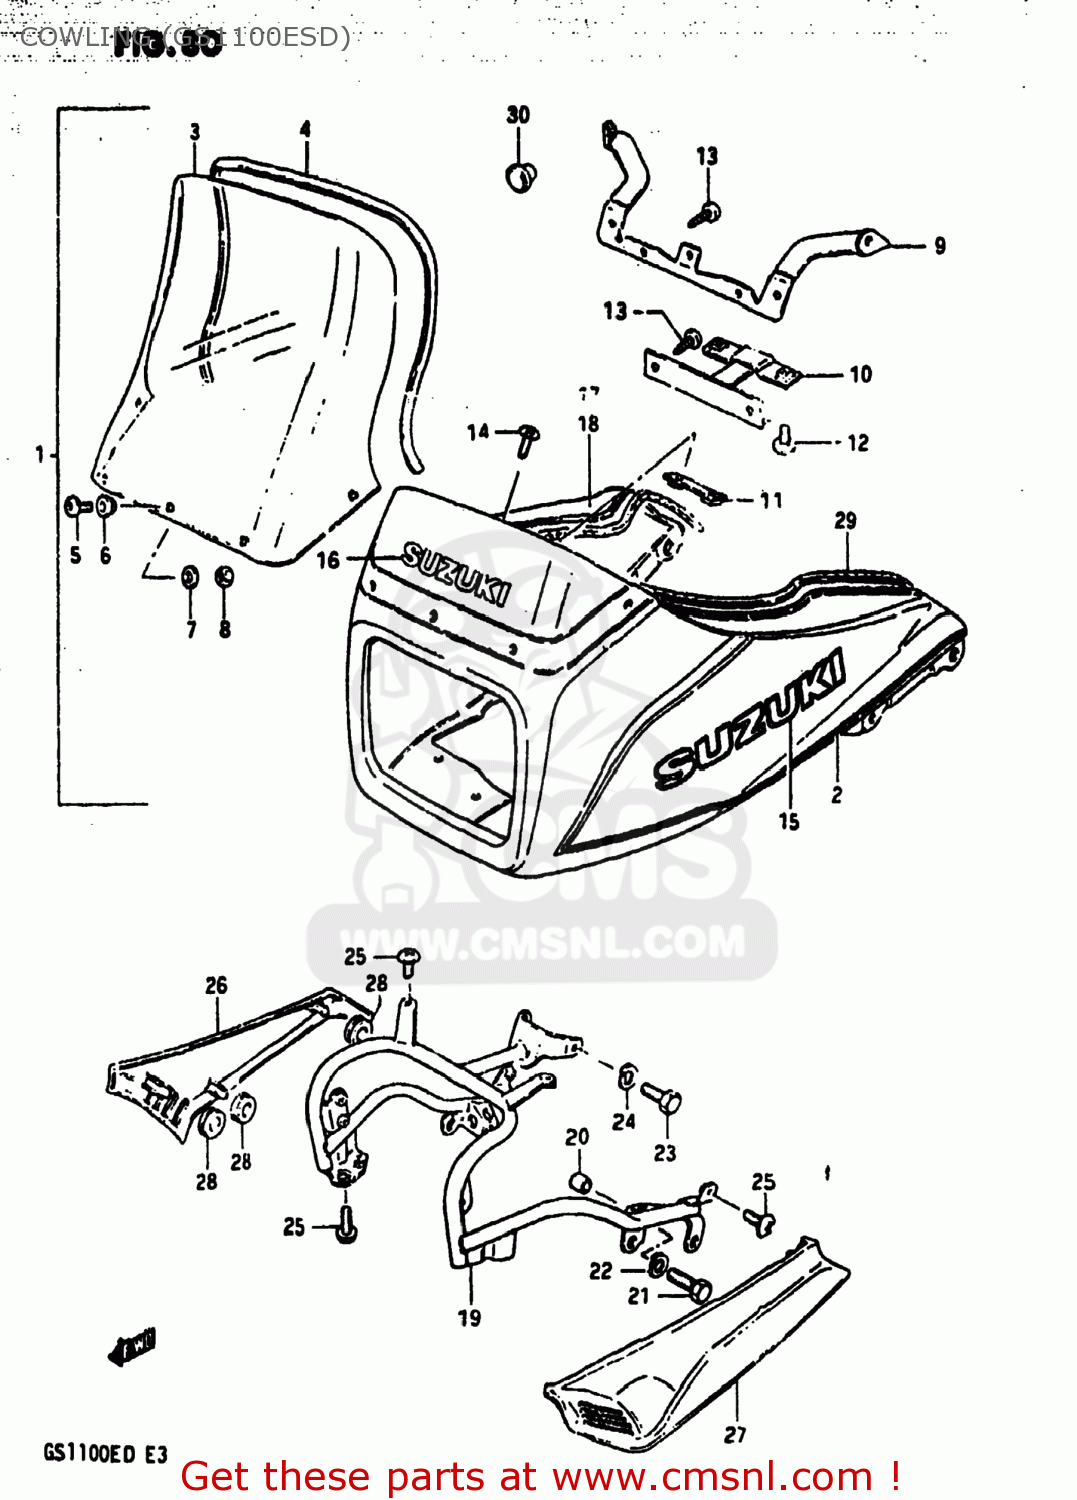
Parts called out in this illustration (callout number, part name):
1	BODY ASSEMBLY,COWLING
2	TAPE SET,COWLING
3	WINDOW,COWLING
4	MOLDING
5	SCREW(5X20)
6	CUSHION
7	WASHER
8	NUT
9	BRACE,COWLING,UPPER
10	BRACE,COWLING,LOWER
11	BRACKET
12	SCREW
13	SCREW
14	SCREW RH & LH
15	EMBLEM
16	EMBLEM,HEADLAMP
17	TAPE,RIGHT
18	TAPE,LEFT
19	BRACE,COWLING
20	SPACER,COWLING BRACE
21	BOLT (8X30)
22	LOCK WASHER
23	BOLT
24	LOCK WASHER
25	SCREW 6X12
26	COVER,COWLING,RIGHT
27	COVER,COWLING,LEFT
28	CUSHION
29	MOLDING,FUEL TANK
30	PLUG(OD:12)
